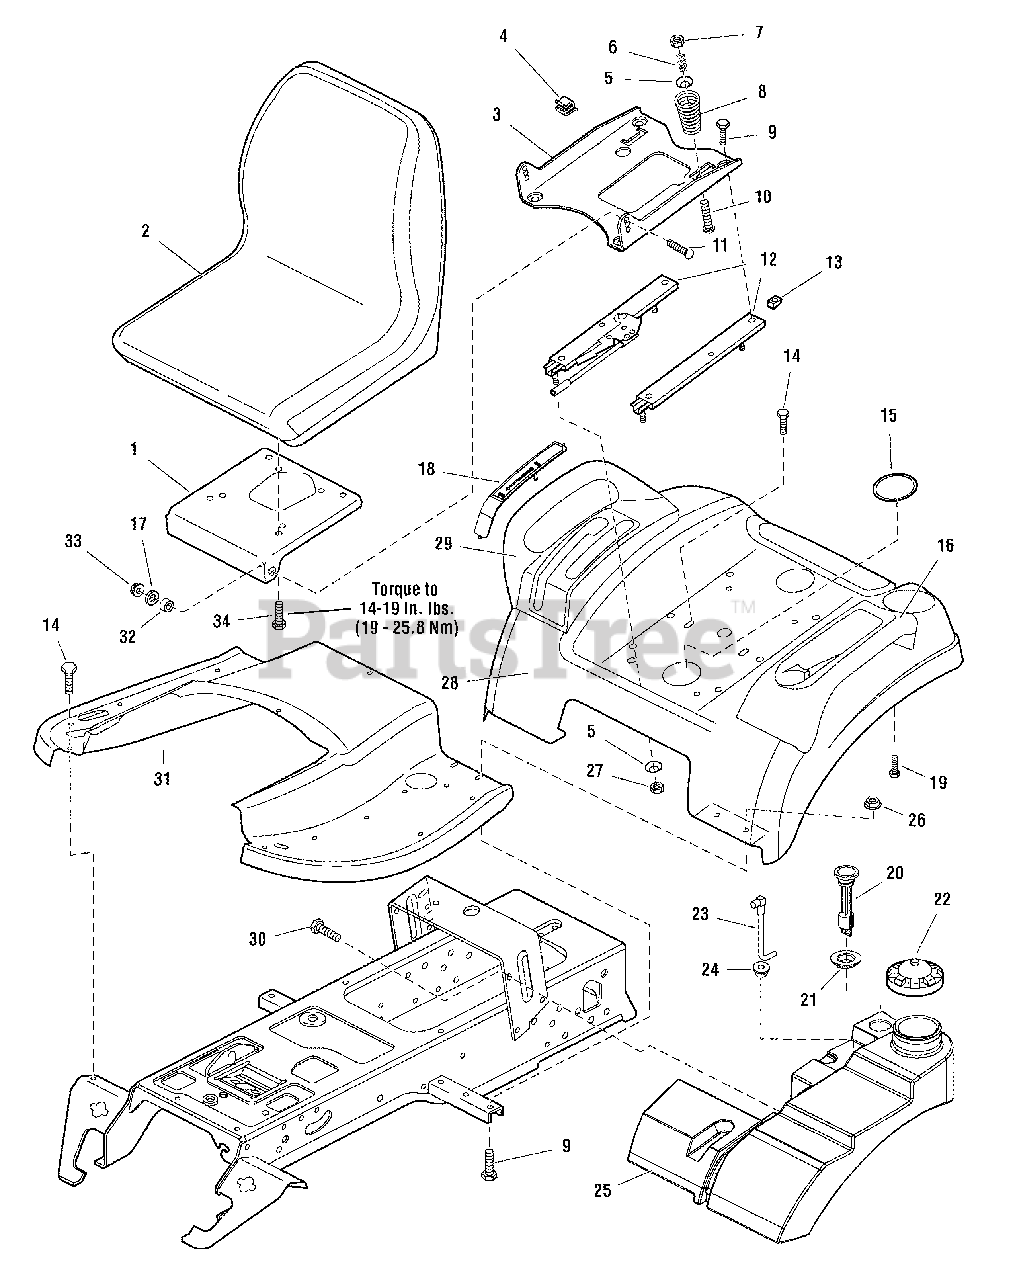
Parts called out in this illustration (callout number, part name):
1	BRACKET, Seat
2	SEAT, 15" Back, Snapper Logo
3	SUPPORT, Seat
4	CLIP, Wire
5	WASHER, Spring
6	SPRING, Compression
7	NUT, Hex Lock ESNA Light, 5/16-18
8	SPRING, Compression
9	CAPSCREW, Hex Head Whizlock, 5/16-18 x 3/4
10	CARRIAGE BOLT, 5/16-18 x 2
11	CARRIAGE BOLT, 3/8-16 x 1
12	SLIDE, Seat, (2 Piece Set)
13	NUT, Speed, Lug Type, 5/16-18
14	CAPSCREW, Hex Head Taptite, 5/16-18 x 5/8
15	PLUG, Hole Black
16	POD, LH, w/Cup Holder
17	WASHER
18	COVER, Cruise, w/Symbols
19	CAPSCREW, Hex Head Washer Dog Point, 1/4-20 x 7/8
20	GAS GAUGE
21	GROMMET
22	CAP, Gas
23	TUBE & ELBOW ASSEMBLY
24	BUSHING
25	TANK, Fuel
26	NUT, Hex Whiz Lock, 5/16-18
27	NUT, Hex KEPS, 5/16-18
28	DECK, Seat, Red
29	POD, RH, W/2 Slots
30	CAPSCREW, Hex Head Whizlock, 5/16-18 x 5/8
31	TUNNEL, Footrest, Red
32	SPACER
33	NUT, Hex Flange Lock, 3/8-16
34	CAPSCREW, Hex Head Flange Lock, 5/16-18 x 3/4
